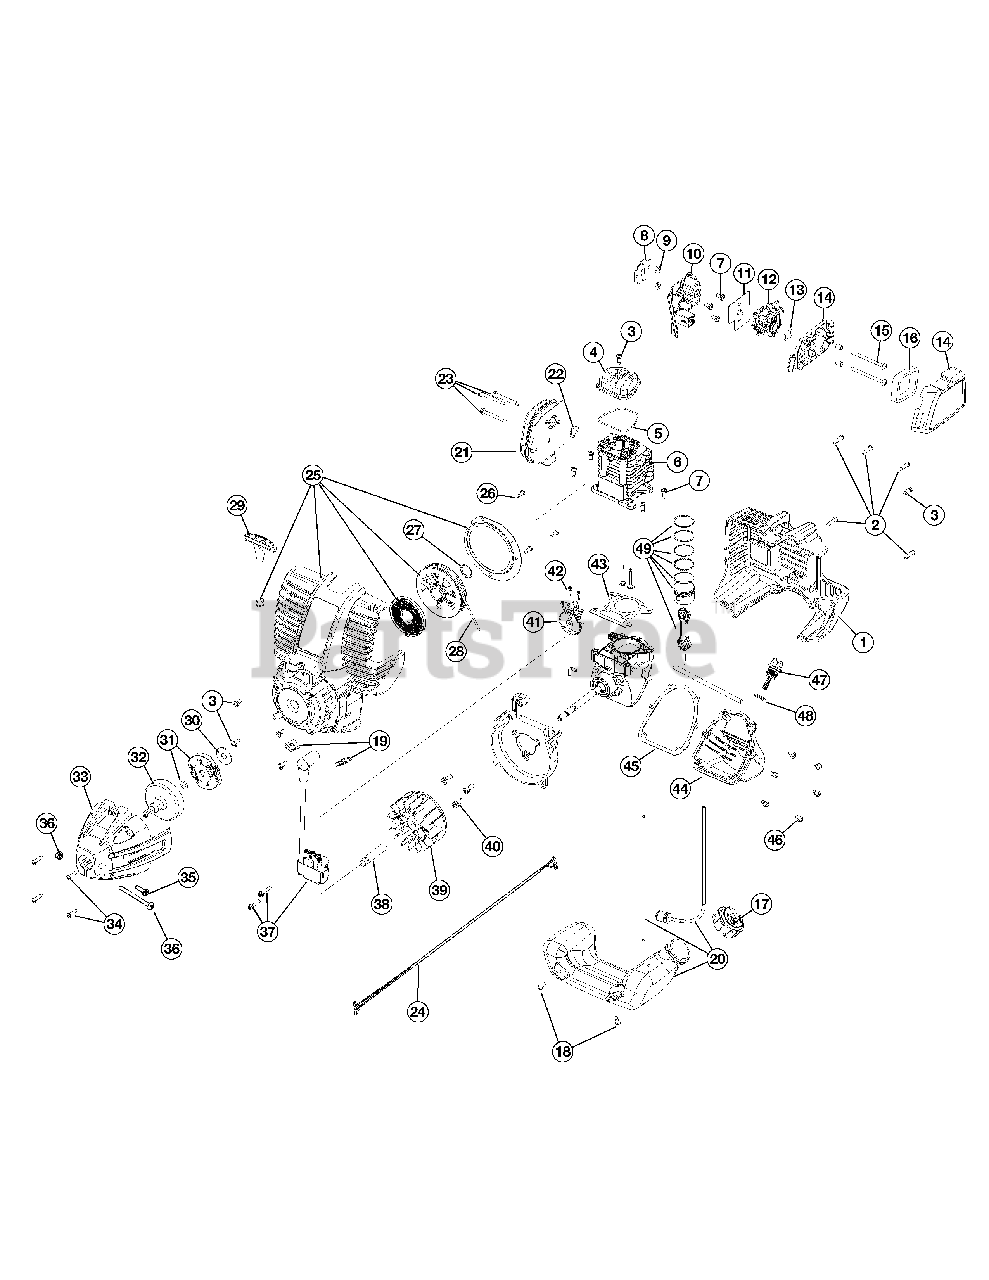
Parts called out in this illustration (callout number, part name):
1	Engine Cover
4	Valve Cover
5	Valve Cover Gasket
6	Cylinder Assembly
7	Cylinder Screw
8	Insulator Gasket
10	Insulator
11	Carburetor Gasket
12	Carburetor w/Primer
13	Carburetor O-Ring
14	Air Filter Cover Assembly
15	Air Filter Mounting Screw
16	Air Filter
20	Fuel Tank Assembly
21	Muffler Assembly
22	Muffler Gasket
23	Muffler Mounting Screw
25	Starter Housing Assembly
26	Plate Screw
29	Pull Handle
31	Clutch Assembly
32	Clutch Drum
33	Clutch Cover Assembly
34	Cover Screw
35	Anti-Rotation Screw
36	Clamping Screw Assembly
37	Ignition Module Assembly
40	Shroud Screw
41	Cam Bracket Assembly
42	Cam Bracket Screw
43	Cylinder Gasket
44	Oil Pan
45	Oil Pan Gasket
46	Oil Pan Screw
47	Dipstick Assembly
49	Piston Assembly
